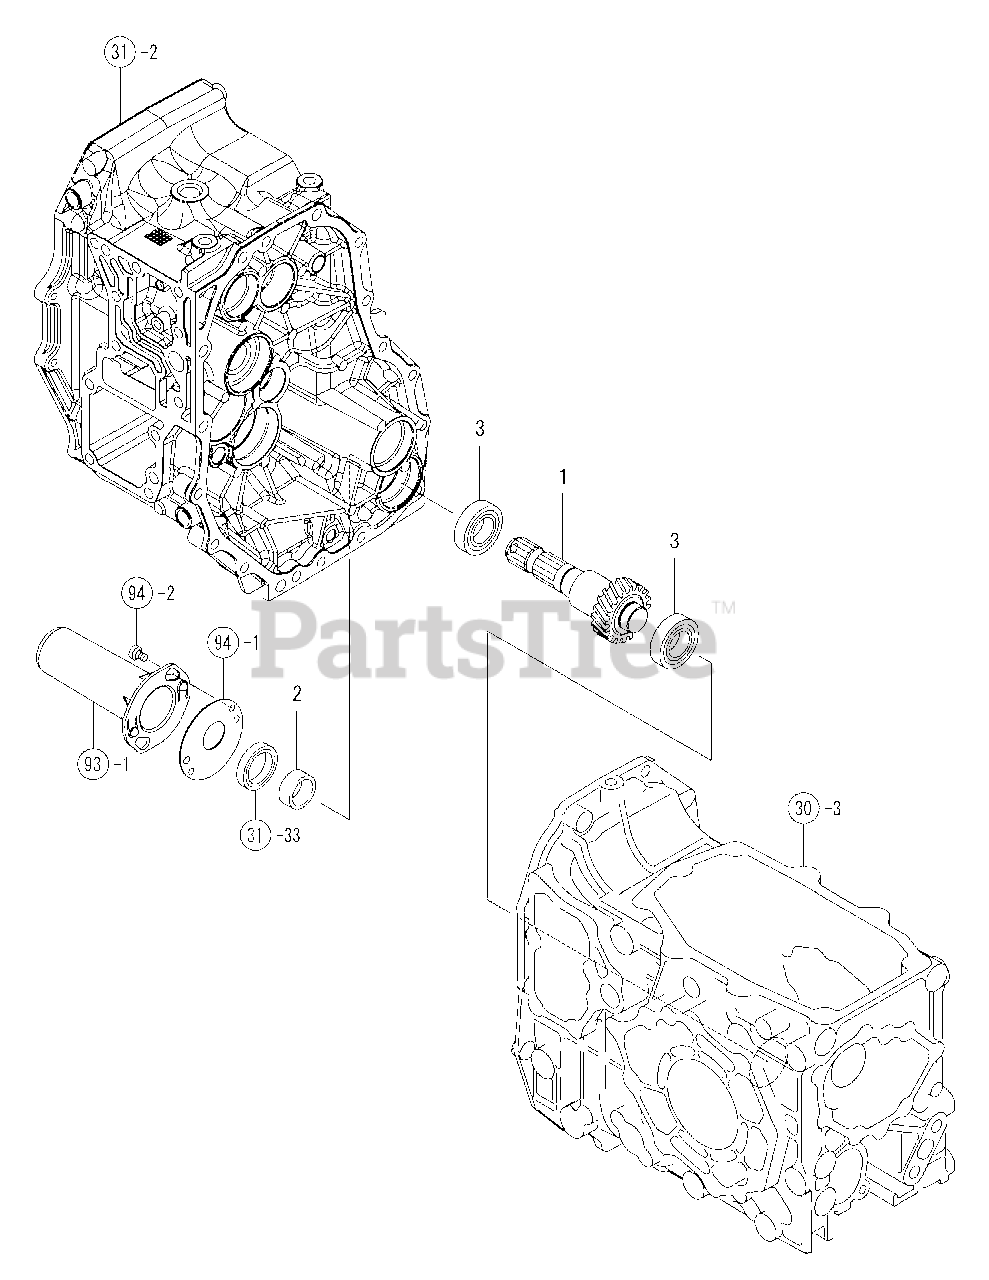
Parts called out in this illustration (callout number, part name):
1	Shaft, Mid PTO
2	Sleeve Si25X30X13
3	Ball Bearing 6005
